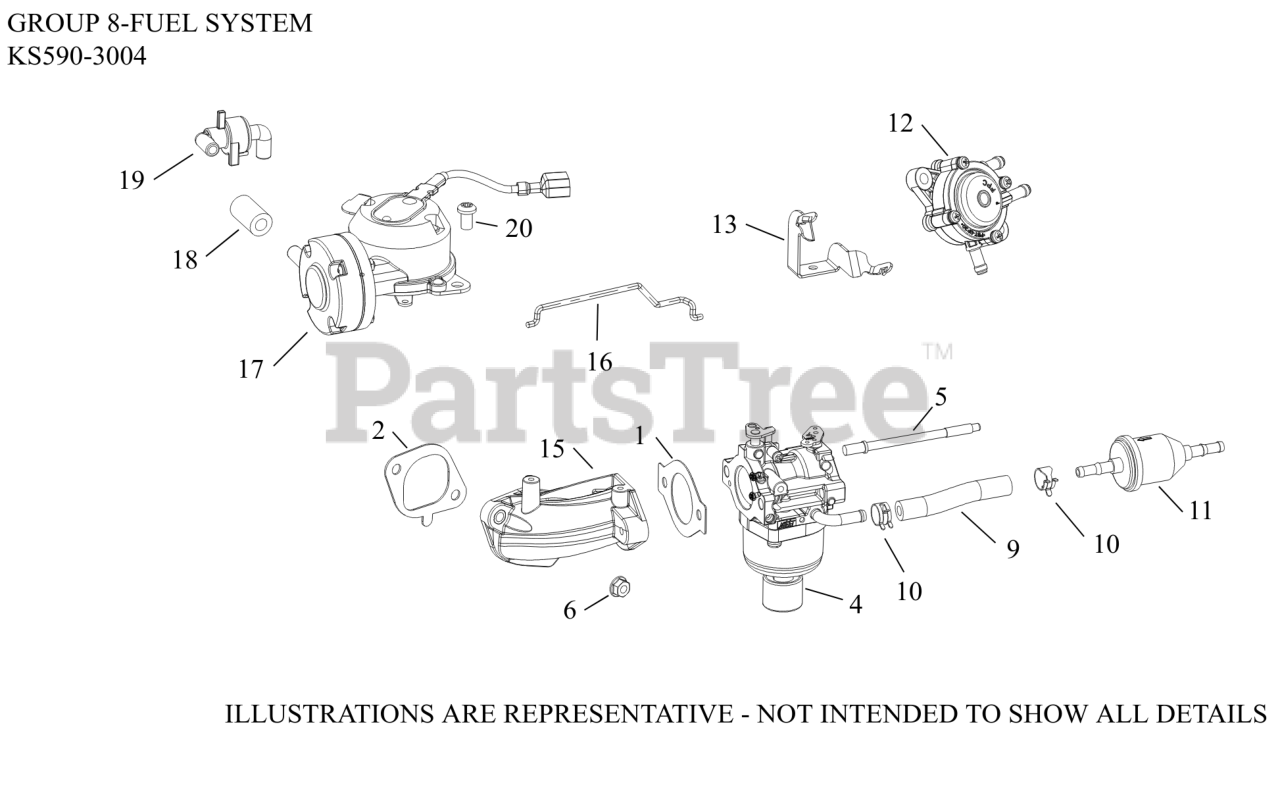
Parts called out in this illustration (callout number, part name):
1	GASKET, CARBURETOR (THROTTLE)
2	GASKET, INTAKE MANIFOLD
4	KIT,CARB(NIKKI)
5	STUD, CARBURETOR
6	NUT, FLG M6X1.0
9	HOSE,LW PERM.FUEL 24.00"-USE 25 111 81-S
10	SPRING CLAMP, HOSE
11	FILTER,FUEL 51 MICRON (FUEL PUMP)
12	PUMP, FUEL (PULSE)-(#2539326S)
13	BRACKET, FUEL PUMP
15	MANIFOLD, INTAKE ASSY
16	LINKAGE, CHOKE
17	DIAPHRAGM ASSY
18	HOSE, VACUUM
19	CHECK VALVE ASSY
20	SCREW, K40 X 1.79 TFS
NI	HIGH ALTITUDE KIT (5000 FT)
NI	KIT, OVERHAUL
NI	KIT, CHOKE SHAFT
NI	KIT, O-RING
NI	KIT, SOLENOID (NIKKI)
NI	KIT, BOWL WITH O-RINGS
NI	KIT, FLOAT & INLET NEEDLE FOR FUEL PUMP
NI	KIT, THROTTLE SHAFT
